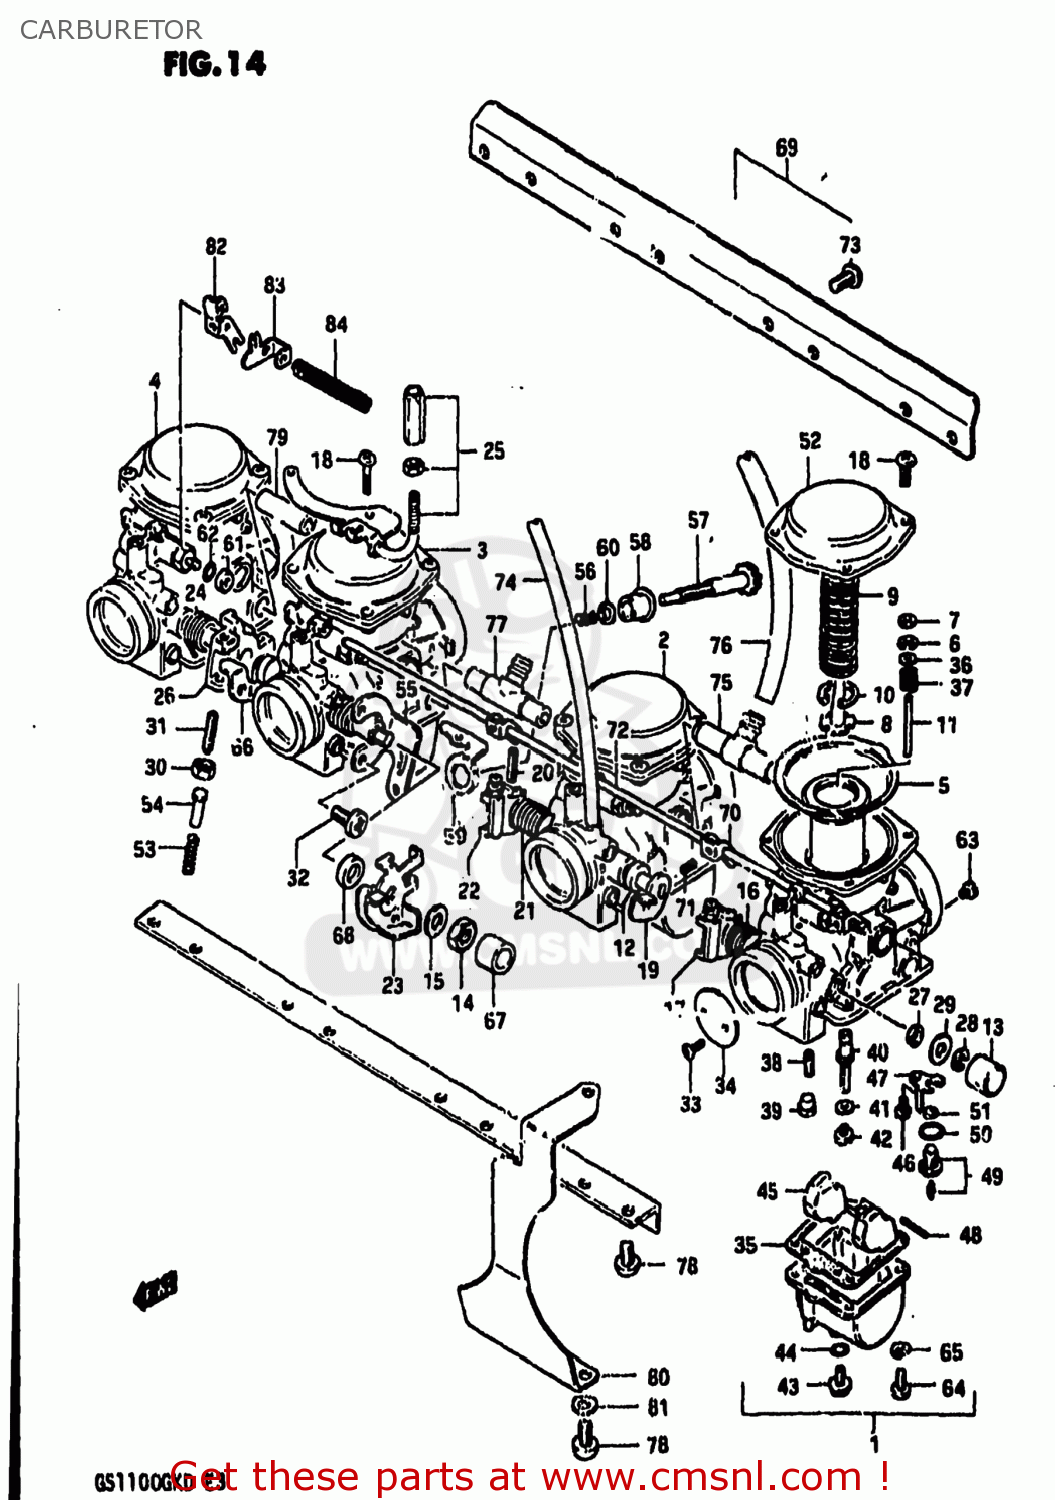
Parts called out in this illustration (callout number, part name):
1	CARBURETOR ASSEMBLY
2	CARBURETOR ASSEMBLY
3	CARBURETOR ASSEMBLY
4	CARBURETOR ASSEMBLY
5	DIAPHRAGM ASSEMBLY
6	CLIP,NEEDLE
7	RING
8	HOLDER,GUIDE
9	SPRING
10	E RING
11	NEEDLE,JET
12	GASKET
13	CAP
14	NUT 8MM
15	WASHER
16	SPRING,THROTTLE SHAFT
17	SHAFT,THROTTLE
18	SCREW
19	SHAFT,THROTTLE
20	PIN,THROTTLE SHAFT
21	SPRING,THROTTLE SHAFT
22	LEVER,THROTTLE SHAFT
23	LEVER ASSEMBLY,THROTTLE
24	SPRING,THROTTLE SHAFT
25	BRACKET,THROTTLE CABLE
26	SHAFT,THROTTLE
27	SEAL
28	E RING
29	GASKET,THROTTLE SHAFT (NAS)
30	NUT
31	SCREW
32	SCREW
33	SCREW
34	VALVE,THROTTLE
35	GASKET,FLOAT CHAMBER (NAS)
36	WASHER
37	SPRING
38	JET
39	PLUG,NEEDLE JET
40	JET,NEEDLE
41	WASHER,NEEDLE NOZZLE
42	JET,MAIN(115)
43	PLUG,DRAIN
44	GASKET (NAS)
45	FLOAT
46	SCREW 4X6
47	PLATE,NEEDLE VALVE FITING
48	PIN,FLOAT
49	VALVE ASSEMBLY,NEEDLE
50	O RING
51	FILTER
52	COVER,DIAPHRAGM
53	SPRING,THROTTLE SCREW
54	PIN,THROTTLE LEVER
55	BRACKET,THROTTLE ADJUST
56	SPRING
57	SCREW
58	BUSH
59	BRACKET,THROTTLE ADJUST
60	WASHER
61	CAP,STARTER VALVE
62	O RING
63	JET,AIR
64	SCREW
65	LOCK WASHER
66	SHAFT,THROTTLE
67	RING
68	RING
69	CARBURETOR ASSEMBLY
70	LEVER
71	SCREW
72	SHAFT,STARTER
73	SCREW
74	HOSE
75	NIPPLE
76	HOSE,CARBURETOR
77	NIPPLE
78	SCREW
79	NIPPLE
80	CLAMP
81	WASHER
82	PLATE,CHOKE CABLE
83	LEVER,CHOKE CABLE
84	SPRING,CHOKE CABLE
